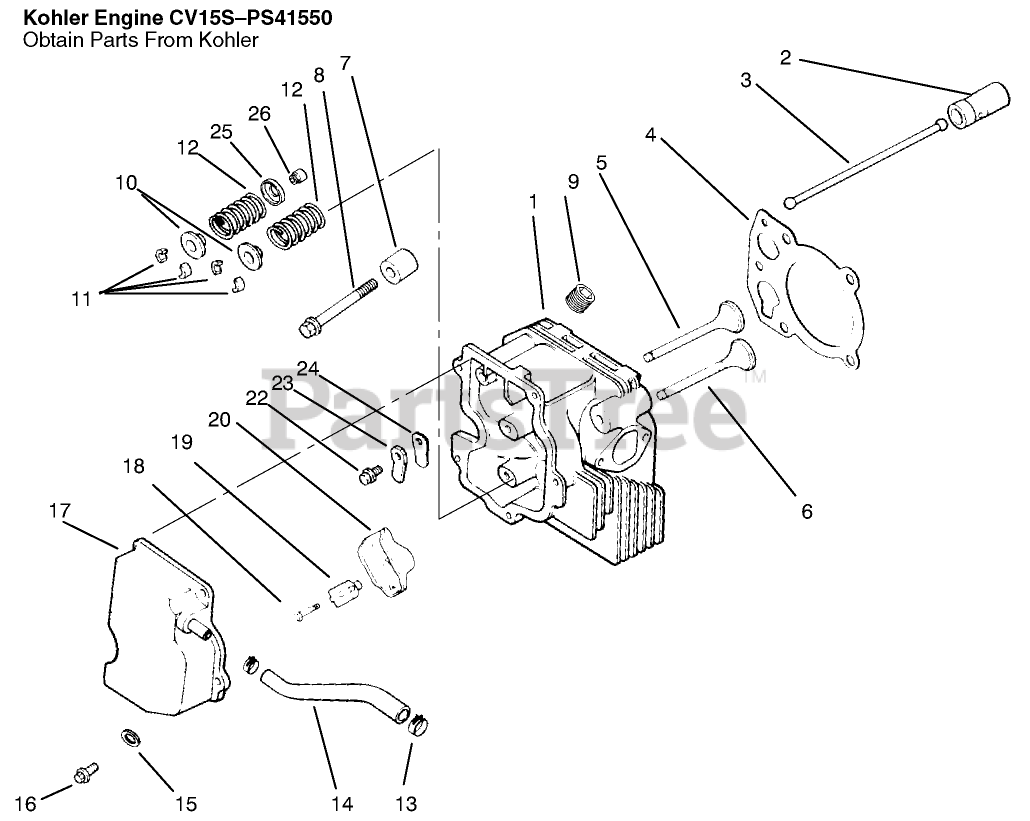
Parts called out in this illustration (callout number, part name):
1	Cylinder Head
2	Lifter-Valve
3	Rod-Push (Only On: 72042,72043,72062,72063)
4	Gasket-Cylinder Head
5	Valve-Intake STD (Only On: 72042, 72063, 72062, 72043)
5	Valve-Intake .25 (Only On: 72042,72043,72062,72063)
6	Valve-Exhaust STD (Only On: 72042,72043,72062,72063)
6	Valve-Exhaust .25 (Only On: 72042, 72063, 72062, 72043)
7	Spacer-Head Bolt Exhaust (Only On: 72042, 72063, 72062, 72043)
8	Screw M10x1.5x80 (Only On: 72042, 72063, 72062, 72043)
10	Cap-Valve Spring
11	Kit-Retainer
12	Spring-Valve Intake (Only On: 72042, 72063, 72062, 72043)
13	Clamp
14	Hose-Breather (Only On: 72042, 72063, 72062, 72043)
15	Washer-Flat (Only On: 72042, 72063, 72062, 72043)
17	Cover-Valve W/Nipple (Only On: 72042, 72063, 72062, 72043)
19	Pivot-Rocker Arm
20	Arm-Rocker
23	Retainer-Reed
24	Reed-Breather
25	Retainer-Spring
26	Seal-Valve Stem
